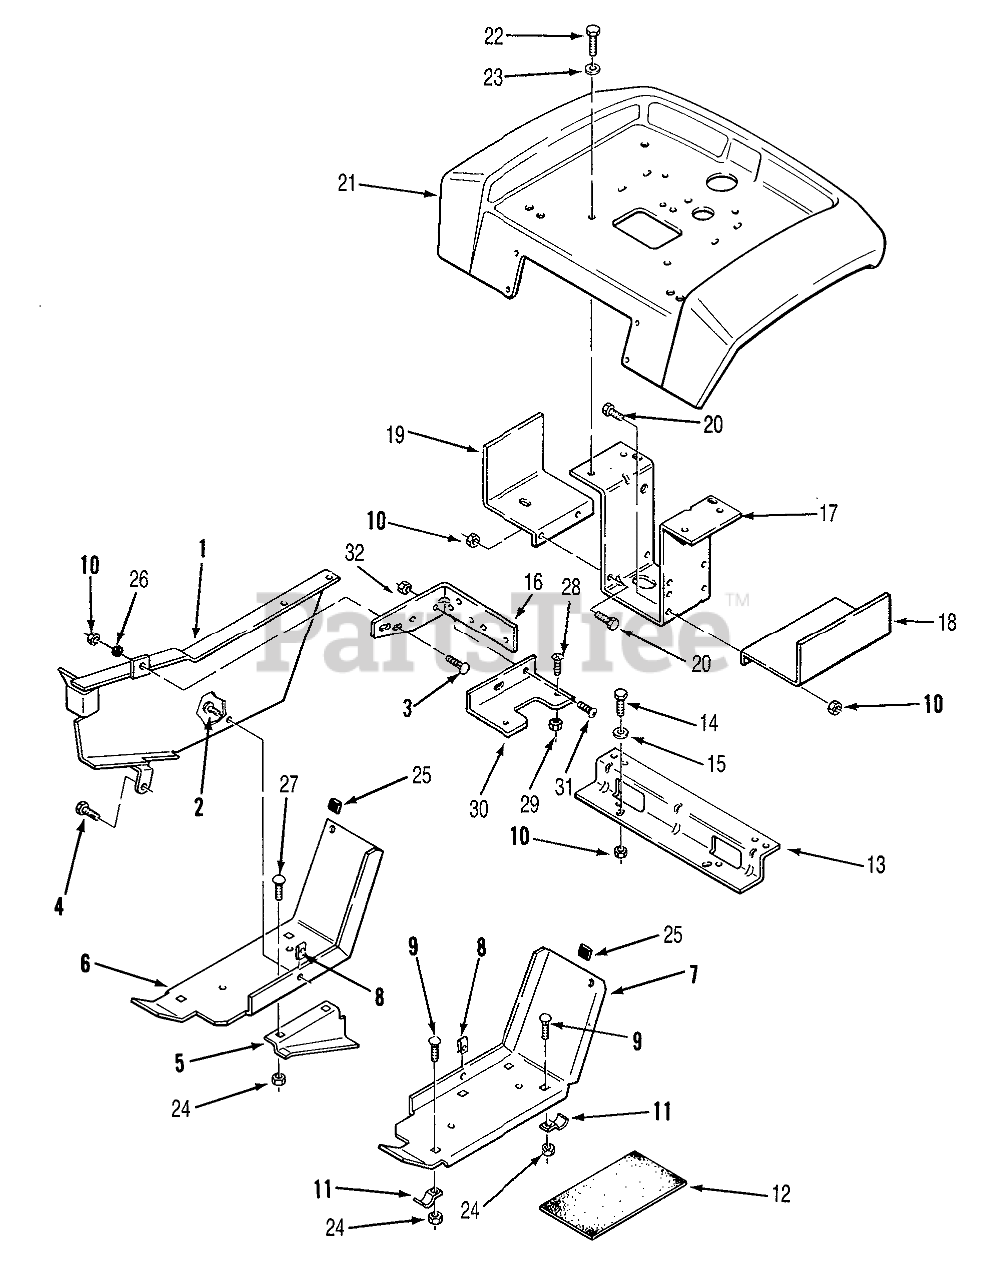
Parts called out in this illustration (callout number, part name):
1	Belt Guard
2	Screw
3	Bolt
4	SCREW
5	GUID-LOWER BLTR
6	Footrest-RH
7	FOOTREST LH R
9	BOLT-CARR
10	Nut
11	BRACKET
12	PAD FOOTREST
13	BRACKET-FENDER B
14	Bolt
15	WASHER 5/16 SAE
16	BRACKET-BELTB
17	Bracket-Fender Support
18	Fuel Tank Support LH
19	Support-FueITank RH
20	Bolt
21	Fender
22	SCREW
23	WASHER 5/16 SAE
24	Nut
25	BUMPER
26	NUT-PUSH
27	BOLT-CARR 5/16 SN
29	Nut
30	BRKT-FUS HLDERB
31	H H C S
32	Nut
